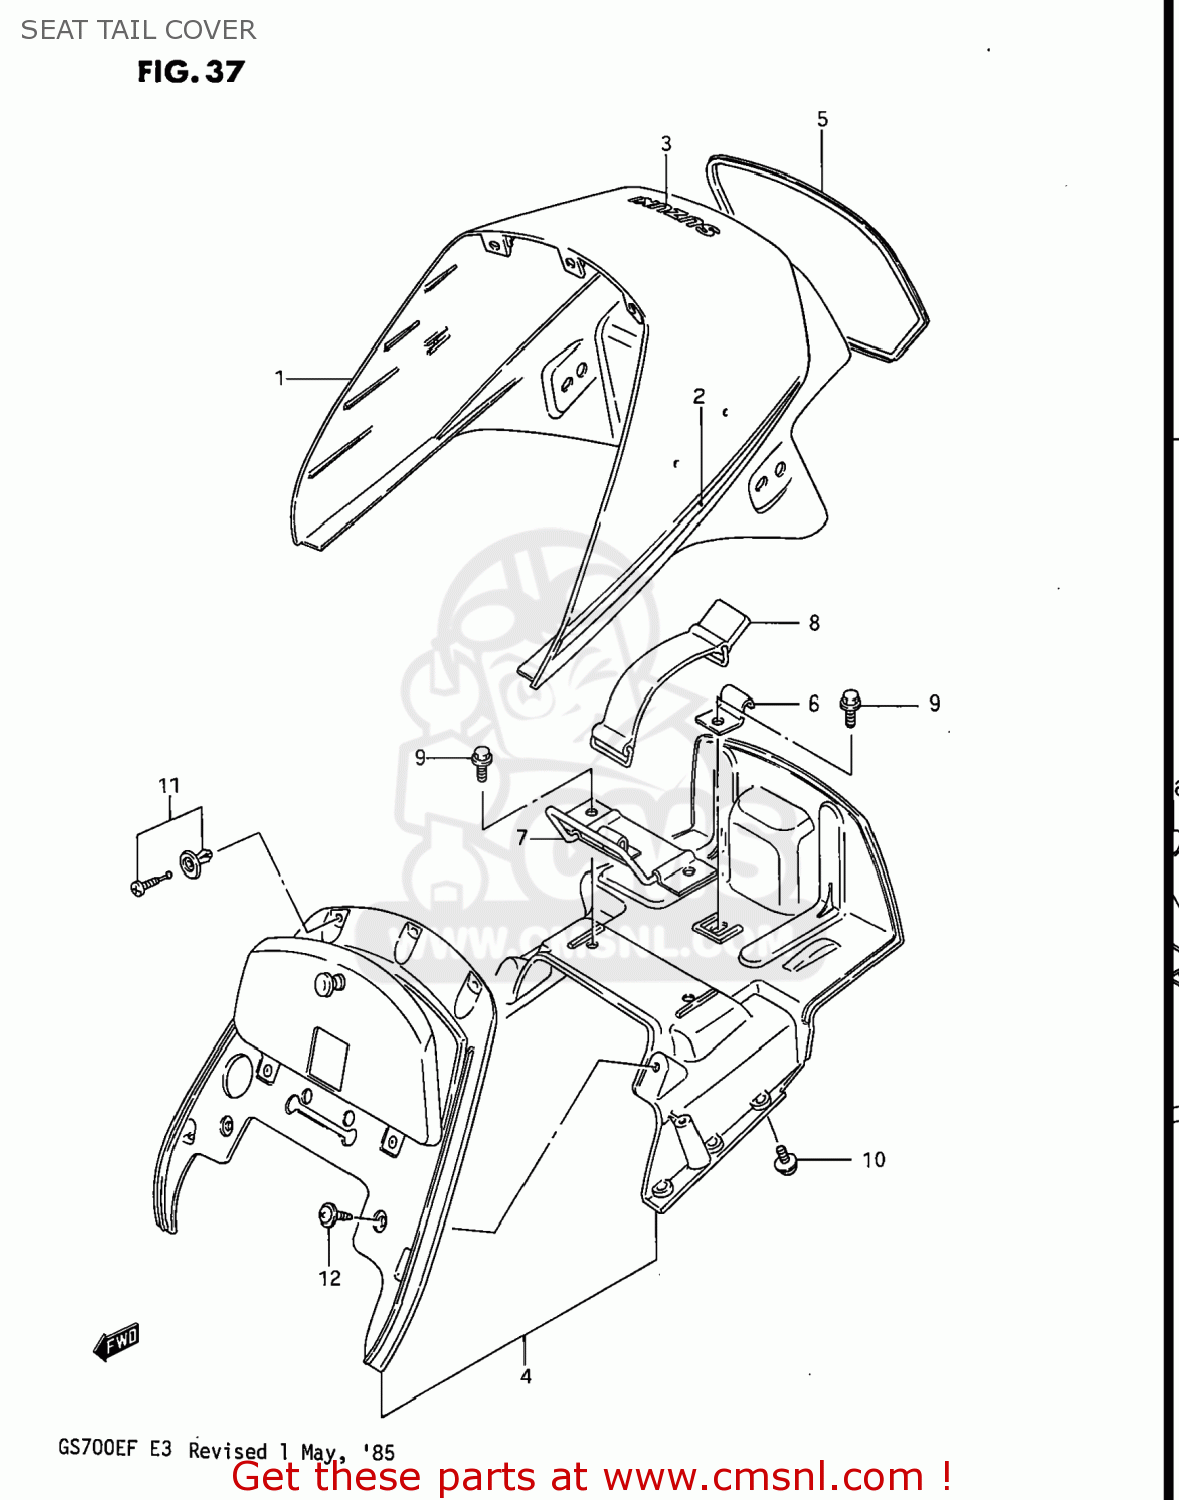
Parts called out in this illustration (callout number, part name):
1	COVER,SEAT TAIL
2	TAPE SET,SEAT TAIL COVER
3	EMBLEM
4	FLAP,SEAT TAIL COVER
5	MOLDING,SEAT TAIL COVER
6	PLATE,CHAIN LOCK HOLDER
7	PLATE,SEAT HOOK
8	BAND
9	BOLT
10	SCREW
11	CLIP
12	SCREW
